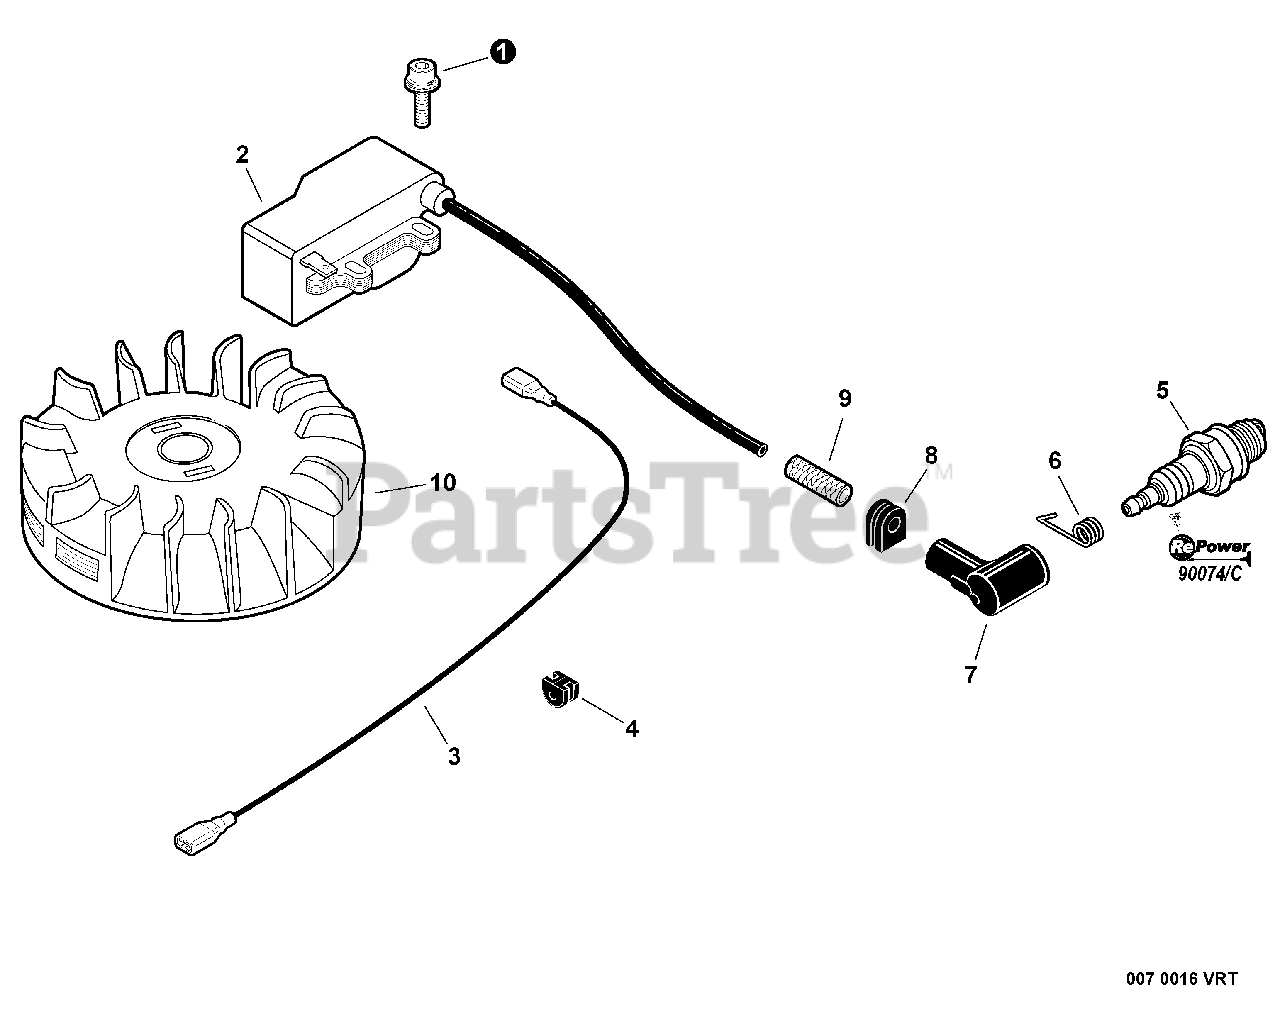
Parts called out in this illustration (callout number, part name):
1	SCREW - 4X20
2	COIL, IGNITION
3	LEAD - IGNITION
5	SPARK PLUG -- BPM-8Y
5	SPARK PLUG -- BPMR-8Y
6	TERMINAL, SPARK PLUG CAP
7	CAP, SPARK PLUG
9	TUBE, INSULATOR
10	FLYWHEEL
11	RePower TUNE-UP KIT
